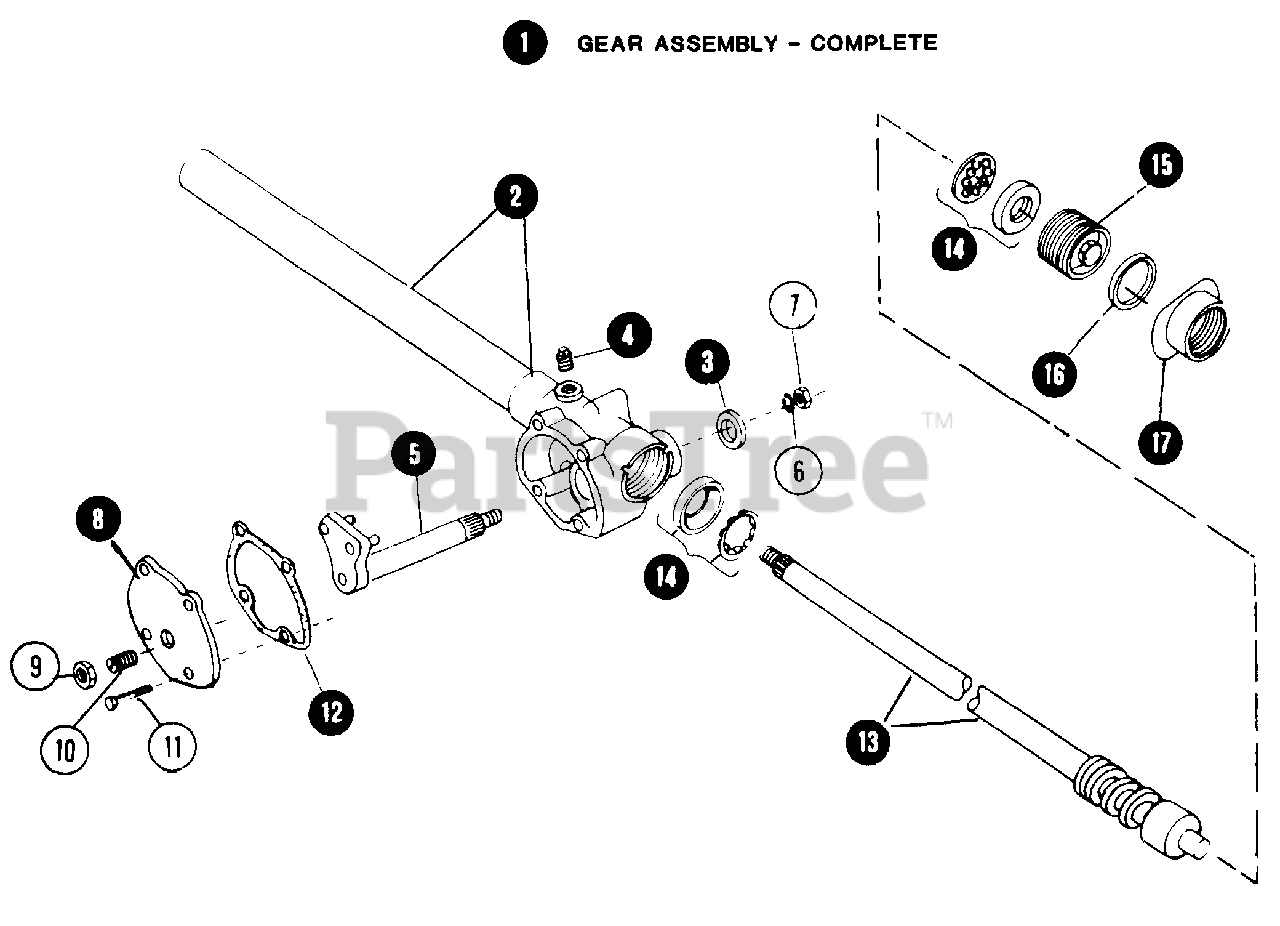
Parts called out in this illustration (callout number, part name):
1	STEERING GEAR ASSEMBLY
2	HOUSING - ASSEMBLY
3	SEAL, OIL
4	PLUG, 1/4 PIPE
5	SHAFT, LEVER - ASSEMBLY
6	WASHER, 5/8 LOCK
7	NUT, 5/8 N.F. HEX
8	COVER, SIDE
9	NUT, ADJUSTING SCREW LOCK
10	SCREW, ADJUSTING
11	BOLT, COVER RETAINING
12	GASKET, SIDE COVER TO HOUSING
13	CAM & TUBE ASSEMBLY
14	KIT, BALL & CUP
15	PLUG, HOUSING END
16	SEAL, HOUSING END PLUG
17	NUT, END PLUG LOCK
